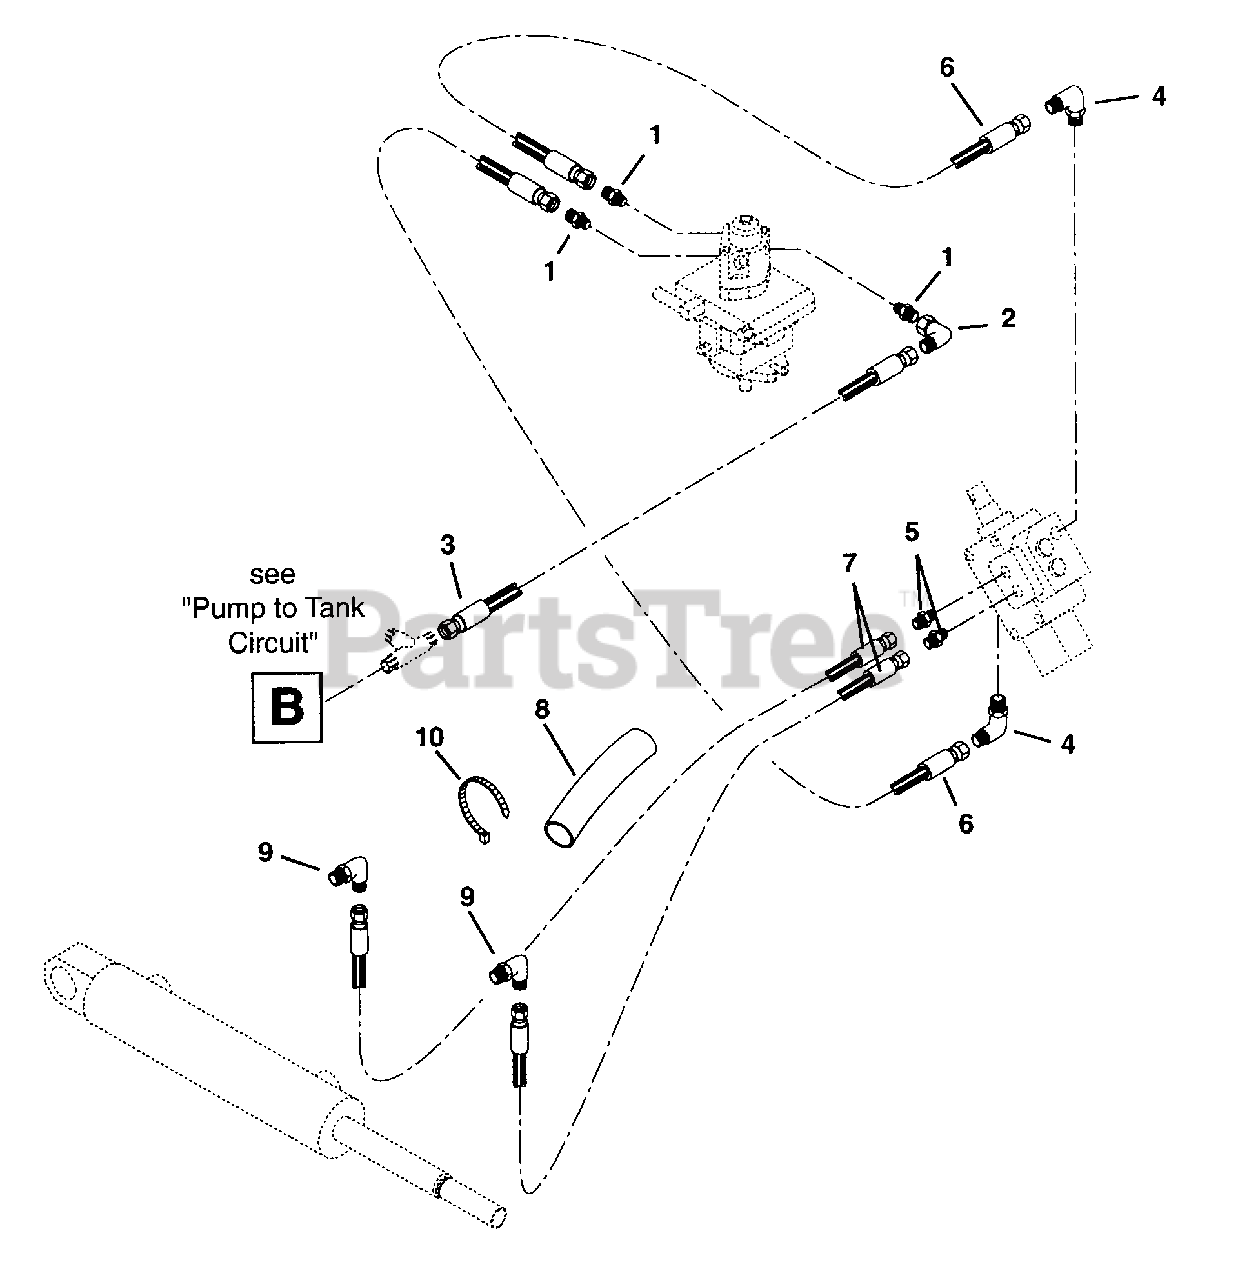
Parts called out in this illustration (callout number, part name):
2	Adapter
3	Hose-Hydraulic Valve to Tank
4	Adapter
5	Adapter
6	Hose Hydraulic .38 27.75 Long
7	Hose-Hydraulic .25 40.5" Long
8	Sleeve Protective 24"
9	Adapter
10	Cable Tie
